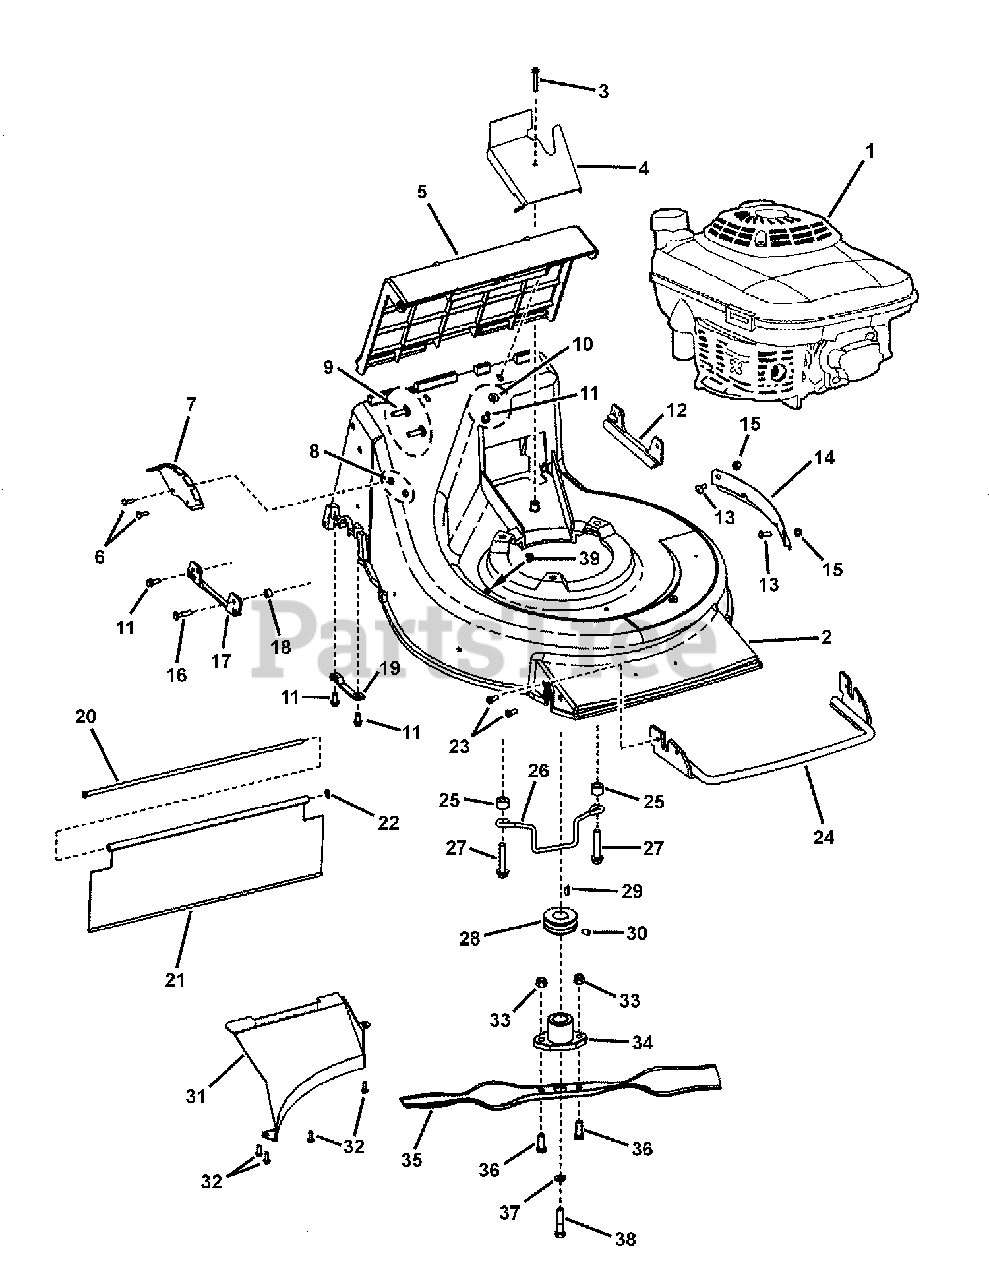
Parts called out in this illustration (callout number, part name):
1	* ENGINE, 6.0 H.P. Kawasaki OHV, Euro, Mod. FJ180V-DS54-R
2	DECK, 21" Cast Aluminum Short (Red)
3	SCREW, #10-24 x 1-1/2" Slotted Hex Washer Head Self-Tap
4	BELT COVER, Commercial Metal B&S
5	ASSEMBLY, Discharge Door
6	BOLT, #10-24 x 5/8" Flat Head Carriage
7	PLATE, Height Adjust
8	NUT, #10-24 Hex Center Lock
9	BOLT, 5/16-18 x 1" Round Head Carriage GR 5
10	WASHER, .28 x .63 x .06 Flat
11	SCREW, 1/4-20 x 5/8" Hex Washer Face Self-Tap
12	BRACKET, L.H.Stiffener
13	SCREW, 1/4-20 x 5/8" Phillips Truss Head Machine
14	GUARD, Wear
15	NUT, 1/4-20 Hex Nyloc
16	SCREW, 1/4-20 x 1" Hex Head Cap GR 5
17	BRACKET, R.H. Stiffener w/tab
18	SPACER, Stiffener
19	SUPPORT, Rear Axle
20	ROD, Trailing Shield Pivot (1/4" Dia.)
21	SHIELD, Trailing, Commercial Cast
22	PUSHNUT, 1/4" Black
23	SCREW, 1/4-20 x 5/8" Truss Head (Torx)
24	WELDMENT, Crash Bar
25	IDLER SPACER
26	BELT GUIDE (Wireform)
27	SCREW, 3/8-16 x 2" Hex Head Self-Tap
28	PULLEY, Traction Drive (25mm x 2-1/8" O.D.)
29	KEY, Hi-Pro #HP506 (Briggs engine)
30	SET SCREW, 5/16-18 x 1/2" Hex Recess
31	WELDMENT, Baffle
32	SCREW, #10-24 x 5/8" Slotted Hex Washer Head Self-Tap
33	NUT, 3/8-16 Hex Nyloc
34	HUB, Blade Drive, 25mm Internal Dia.
35	BLADE, 21" Bagging
36	SCREW, 3/8-16 x 1" Hex Head Cap, GR 5
37	WASHER, 3/8" Split Lock (Heavy)
38	SCREW, 3/8-24 x 1-3/4" Hex Head Cap GR 5
39	PLUG, Hole (Polyethylene)
